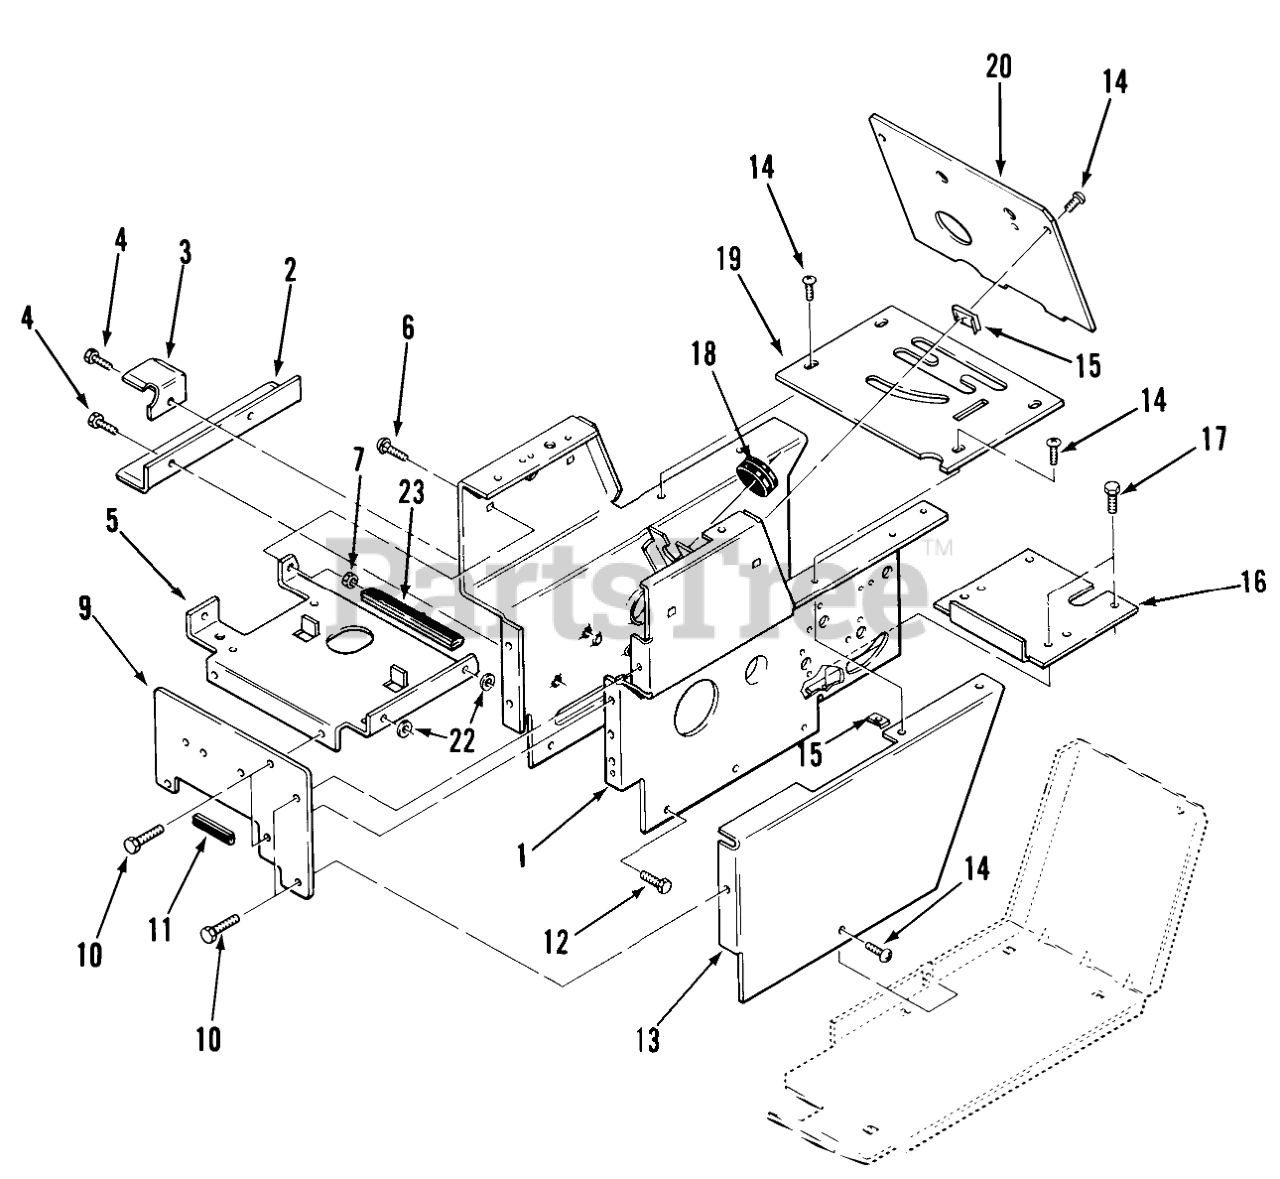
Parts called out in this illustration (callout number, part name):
1	Hoodstand
2	ANGL-BLT GURDB
3	Belt Bracket
3	BRCKET-BLT SUTB
4	SCREW
5	SUPPORT-BATTERY B
6	CARRIAGE BOLT -4
7	Nut
9	Front Plate
10	SCREW
11	EDGE TRIM 2" 102896
12	Bolt
12	SCREW
13	Side Cover LH
14	Screw
16	Cover-Dust
17	SCREW
18	GROMMET
19	Shift Cover Plate GT-1100, GT-1600 Only
19	Shift Cover Plate GT-1800 Only
20	Hoodstand Plate
20	Hoodstand Plate GT-1800 Only
22	WASHER 5/16 SAE
23	EDGE TRIM 5" OF 102896
